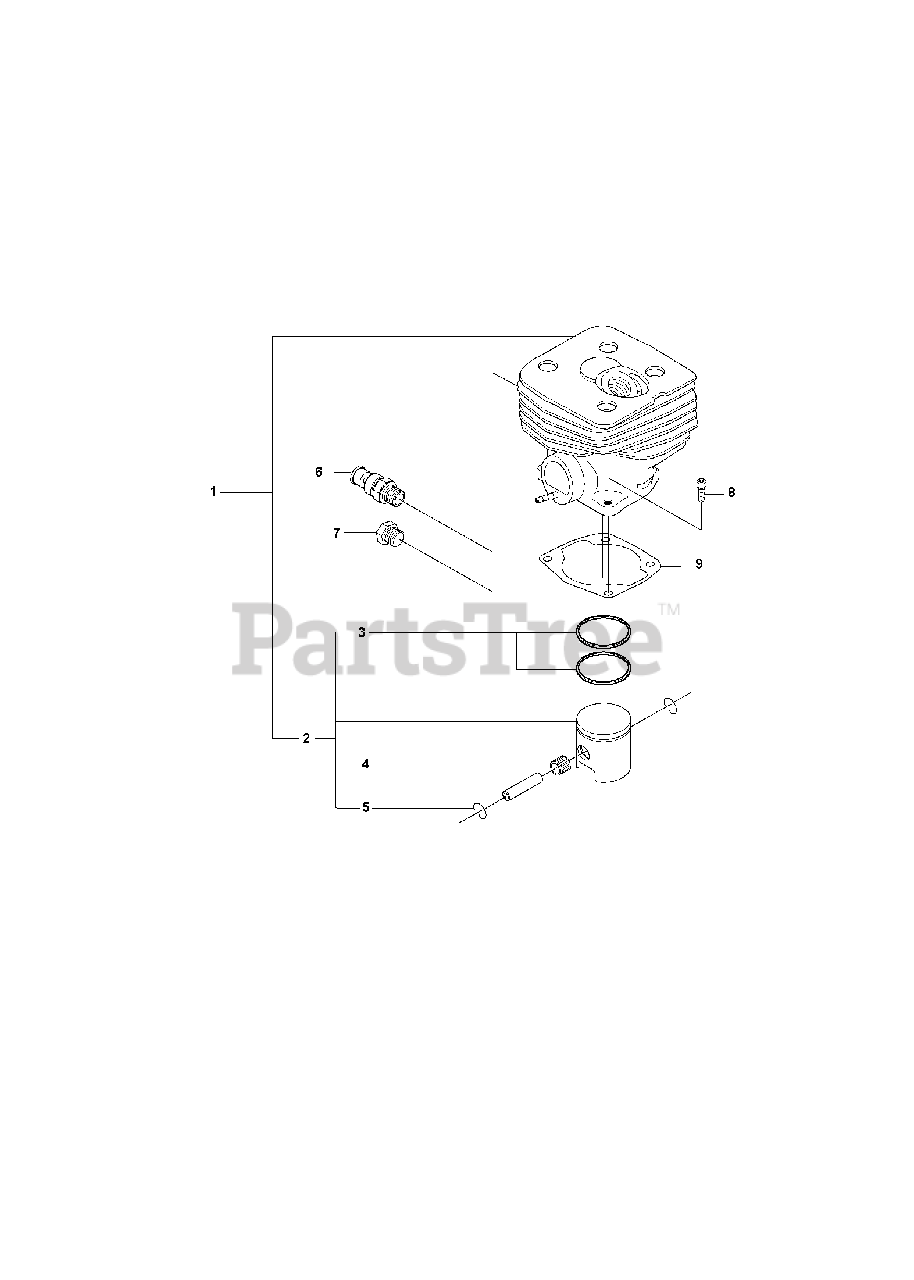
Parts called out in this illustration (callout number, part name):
1	CYLINDER
1	CYLINDER ASSY
2	PISTON ASSEMBLY
2	RP PISTON ASSY
3	PISTON RING
4	RP SUPPORT BUSHING
5	LOCKING RING
6	DECOMPRESSION VALVE
7	CYLINDER PLUG
8	SCREW MC6S 5X20
9	GASKET
